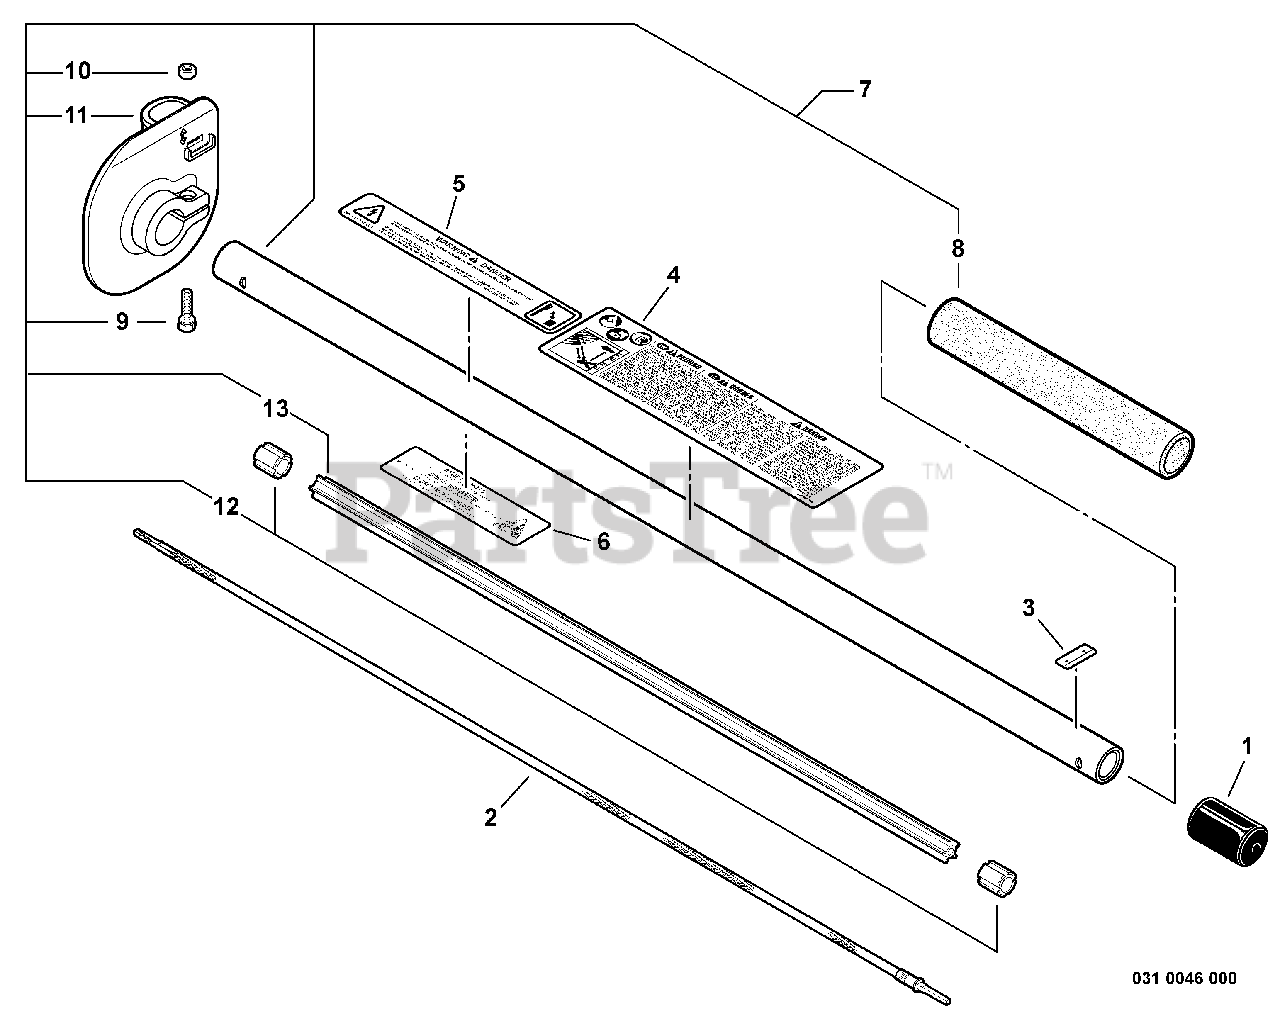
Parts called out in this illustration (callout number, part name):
2	DRIVESHAFT - FLEXIBLE
3	LABEL - ALIGNMENT
4	LABEL - CAUTION
5	LABEL - CAUTION
6	LABEL - CAUTION
7	MAIN PIPE ASSY
9	BOLT - 5X20
11	GUARD
13	LINER - FLEXIBLE
